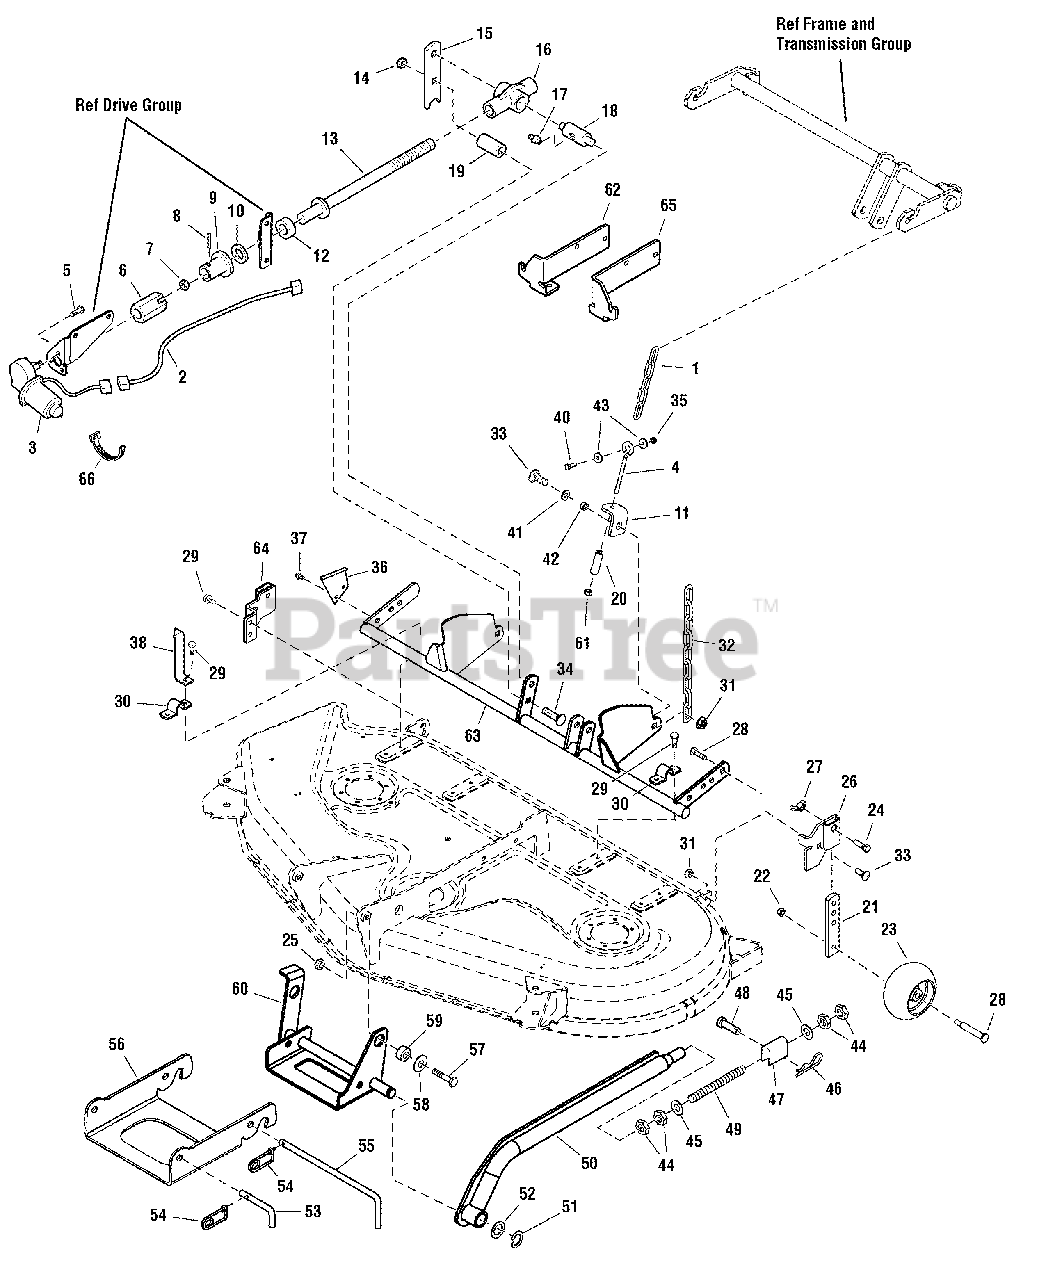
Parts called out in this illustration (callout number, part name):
1	CHAIN ASSEMBLY, 5 Links
2	HARNESS ASSEMBLY
3	MOTOR, Electric
4	BOLT, Tensioner
5	SCREW, Conical Washer, 1/4-20 x 7/8 Dog Point
6	ADAPTER, Motor
7	NUT, Hex, Washer, KEPS, 1/4-20
8	PIN, Spring
10	WASHER, Special, Nylon
11	BRACKET, Lift
12	BEARING, Thrust
13	ROD & SPACER ASSEMBLY
14	NUT, Hex, Toplock Flange,1/2-13
16	COVER, Rod
17	FITTING, Lube
19	SPACER, 1/2 x 7/8 x 1 3/16
20	SPACER, Lift
21	POST, Anti-Scalp
22	NUT, Lock, 3/8-16
23	GAGE WHEEL
24	CAPSCREW, 3/8-18 x 1.25
25	NUT, Hex Flange, 3/8-16
26	SUPPORT ASSEMBLY, Gage Wheel, L.H.
27	NUT, WING, 3/8-16
28	BOLT, Gage Wheel
29	CAPSCREW, Hex Washer Head, 5/16-18 x 3/4
30	STRAP
31	NUT, Hex Flange Lock, ESNA, 3/8-16
32	CHAIN, 8 Link
33	CARRIAGE BOLT, 3/8-16 x 1
34	CARRIAGE BOLT, 1/2-13 x 2-1/2
35	NUT, Hex, Esna Lock, 1/4-20
36	BRACKET, Height of Cut
37	CAPSCREW, Hex Washer Head, Taptite, 5/16-18 x 1/2
38	INDICATOR, Height of Cut
39	SCREW, Set, Square Head, Cup Point, 5/16-18 x 1/2 G8
40	CAPSCREW, Hex, 1/4-20 x 1.00
41	WASHER, Flat 3/8
43	WASHER, Plain, 1/4
44	NUT, Hex, Jam, 5/8-18
45	WASHER, 5/8
46	CLIP, Hair Pin
47	TRUNION
48	PIN, Yoke, Drilled, 1/2 x 2
49	STUD, 5/8-18 x 8-9/16
50	ARM & TUBE ASSEMBLY
51	RING, Retaining, External, 1
52	WASHER, 1
54	PIN, Spring
57	CAPSCREW, Hex Head, 3/8-16 x 1-3/4
58	WASHER, 3/8
60	HITCH ASSEMBLY
61	NUT, Esna Lock, 5/16-18
62	BRACKET, Lift, R.H.
63	ROCKER, Shaft Assembly
64	GAGE, Wheel Assembly, R.H.
65	BRACKET, Lift, L.H.
66	WIRE TIE
